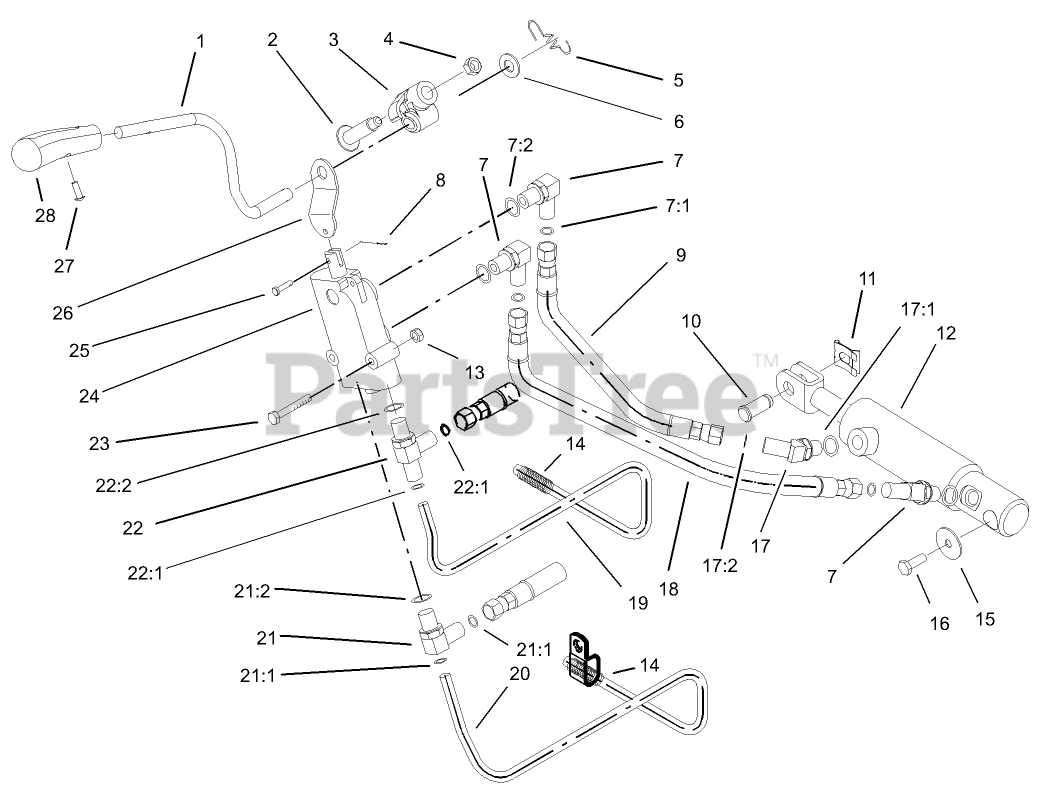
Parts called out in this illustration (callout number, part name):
1	HANDLE-LIFT
2	BOLT-SHOULDER
3	TRUNNION-LEVER, LIFT
4	NUT-JAM, LOCKING
5	SPRING-EXTENSION, LIFT
6	WASHER
7:1	O-RING
7:2	O-RING
8	PIN-COTTER
9	HOSE ASM
10	PIN-CLEVIS
11	CLIP-PIN
12	LIFT CYLINDER ASM
13	NUT-LOCK, NI
14	COVER-BRACE
15	WASHER-FLAT
16	SCREW-THREAD LOCKING
17:1	O-RING
17:2	O-RING
18	HOSE ASM
19	TUBE-HYD
20	TUBE - HYDRAULIC
21:1	O-RING
21:2	O-RING
22	FITTING-STR
22:1	O-RING
22:2	O-RING
23	SCREW-HH
25	PIN-CLEVIS
26	LINK-LIFT
27	SCREW-PPHTF
28	KNOB-LIFT
